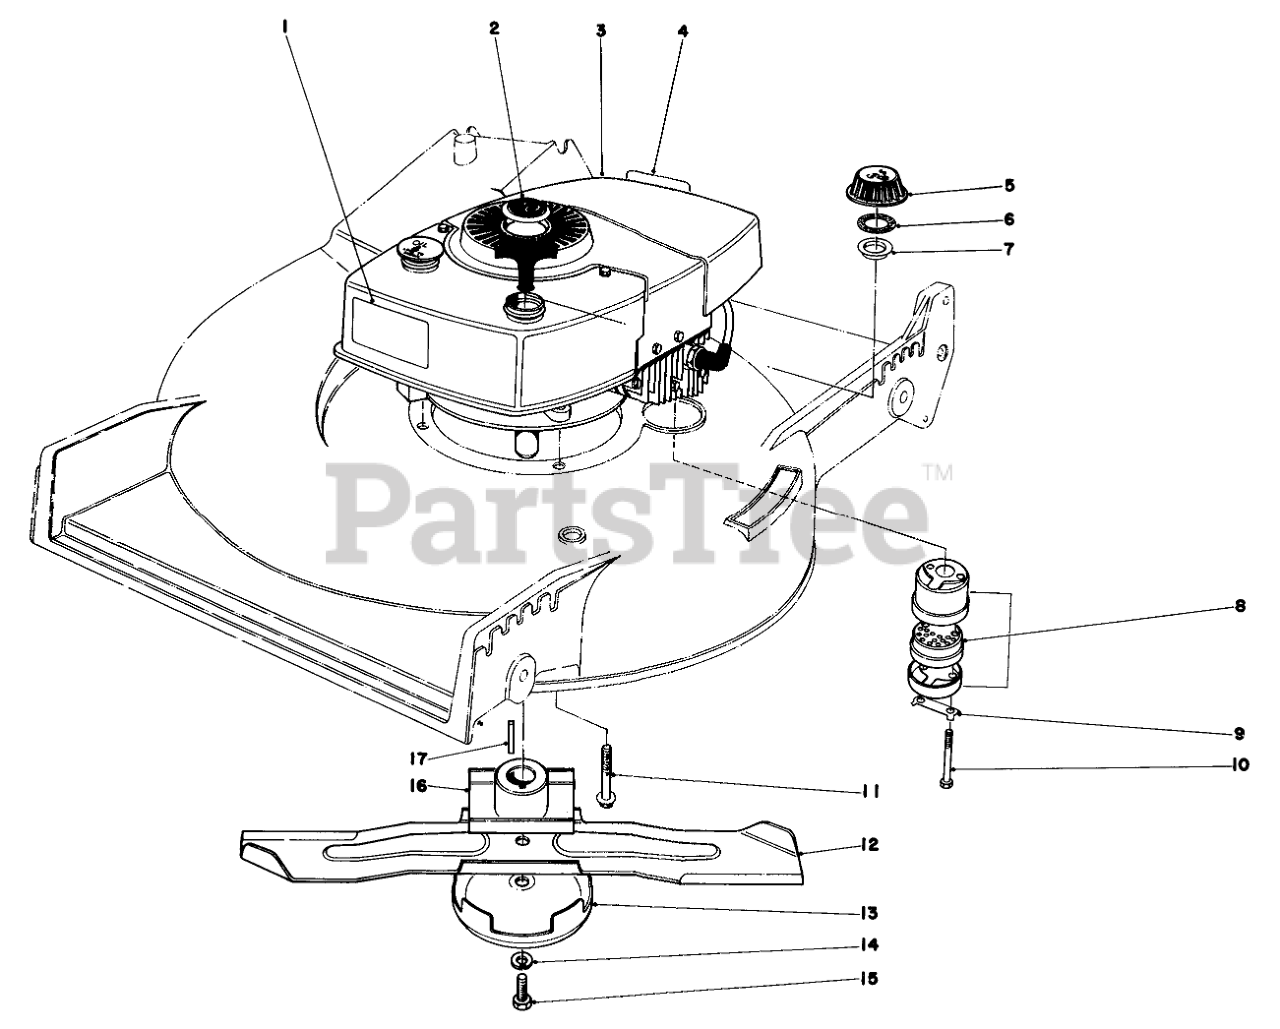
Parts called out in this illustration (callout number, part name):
1	High Torque
2	PLUG BUTTON
3	Engine
4	Decal-Maintenan
5	Gas Cap (Incl. Ref. #6 & 7)
6	GASKET
7	GAS CAP BAFFLE
8	Muffler Assy. (Incl. Ref. #9 & 10)
9	CLIP - LOCKING
10	SCREW-HH
11	SCREW-HWHTF
12	Blade
13	AntiScalp Cup
14	WASHER-LOCK
15	BLADE SCREW
16	BLADE RETAINER WA(BLACK)
17	KEY-SQUARE
